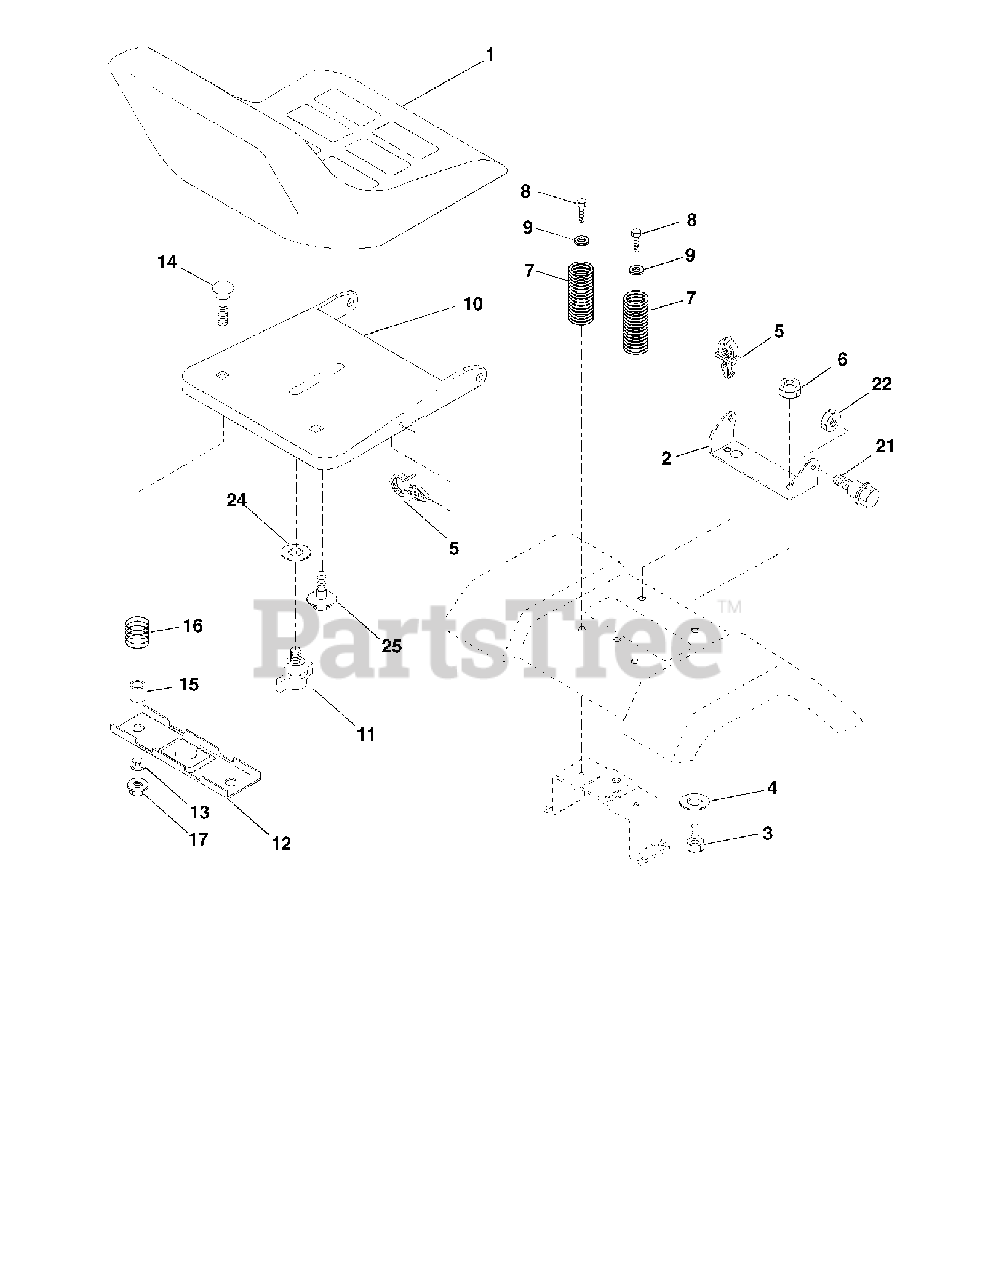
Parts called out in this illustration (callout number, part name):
1	SEAT
2	BRKT,SEAT PIVOT**
3	BOLT, HEX 3/8-16X1
4	WASHER PM
5	PUSH CLIP
6	NUT
7	SPRING COMPRESSION
8	SCREW 3/8-16X1
10	Seat Pan Assembly, 1 Slot
11	KNOB.SEAT.ADJ.WINGNUT
12	BRKT SWITCH
14	BOLT.ROUND.HEAD.SQUARE.NECK
15	SPACER SPLIT 28X.96
17	NUT T
21	BOLT.SHOULDER.5/16-18
22	NUT.71038.31-18.HEX.NYLOCK
25	BOLT,SHOULD
